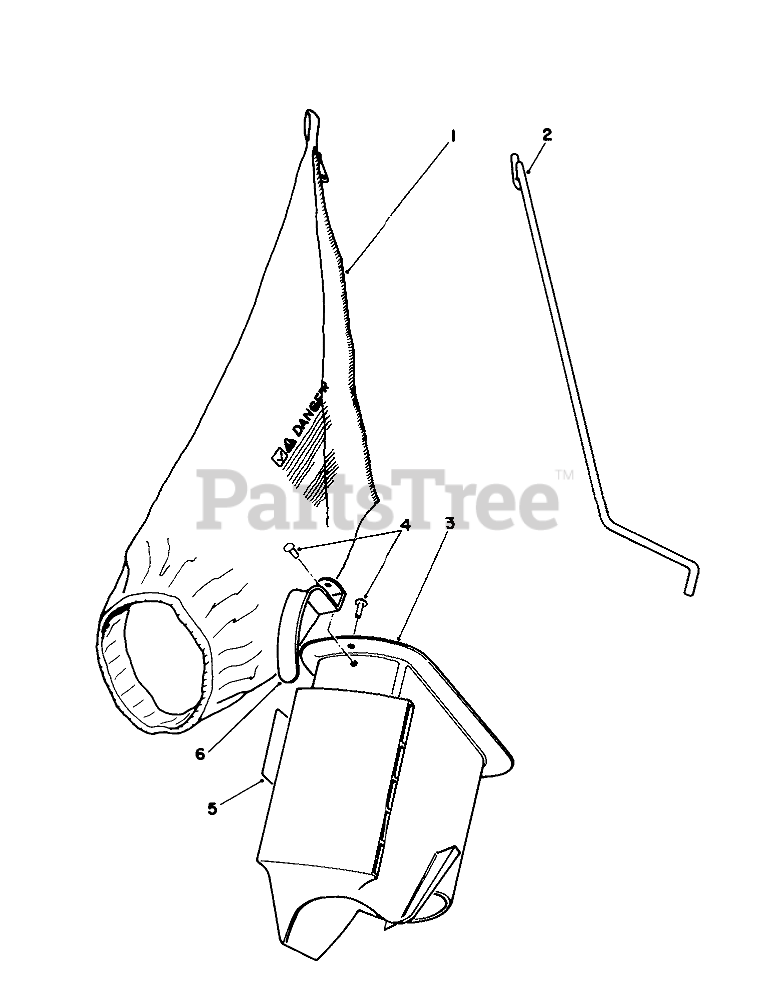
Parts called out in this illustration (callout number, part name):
1	BAG REPLACMNT44-0540
2	BAG ROD
3	Grass Chute (Incl. Ref. #4 & 6)
4	RIVET 3/16 X 7/16
5	BAG CHUTE DECAL
6	HANDLE-GRASS CHUTE
